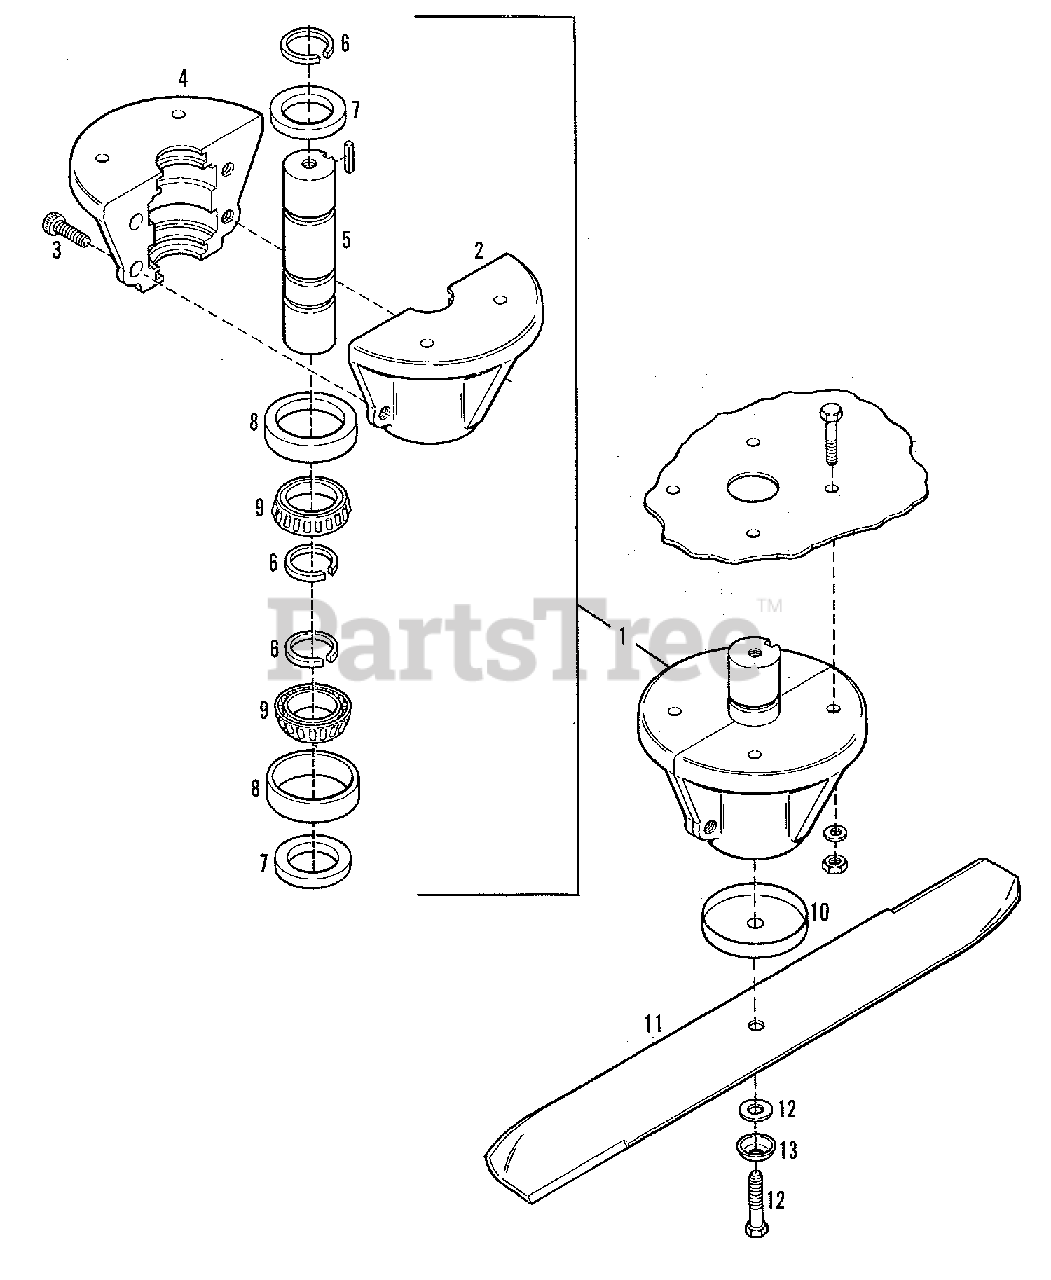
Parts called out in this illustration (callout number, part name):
1	SPINDLE ASSEMBLY, Mower
1	KEY, Square, 1/4 x 1" Long
1	CAPSCREW, 3/8NC x 1-1/4
1	WASHER, Flat, 3/8
1	NUT, Lock, 3/8NC
2	HOUSING, Half, w/o Vent
3	CAPSCREW, Socket Head, 3/8NC x 1-1/2
4	HOUSING, Half, w/ Vent
5	SHAFT, Spindle
6	RING, Retaining, Spindle
7	SEAL, Spindle
8	CUP, Bearing
9	CONE, Bearing
10	WASHER, Spline, Cupped
11	BLADE, Mower
12	CAPSCREW, Blade, L.H. Thread 5/8NC x 1-1/2
12	WASHER, Flat, 5/8
13	WASHER, Belleville Disk, 5/8"
